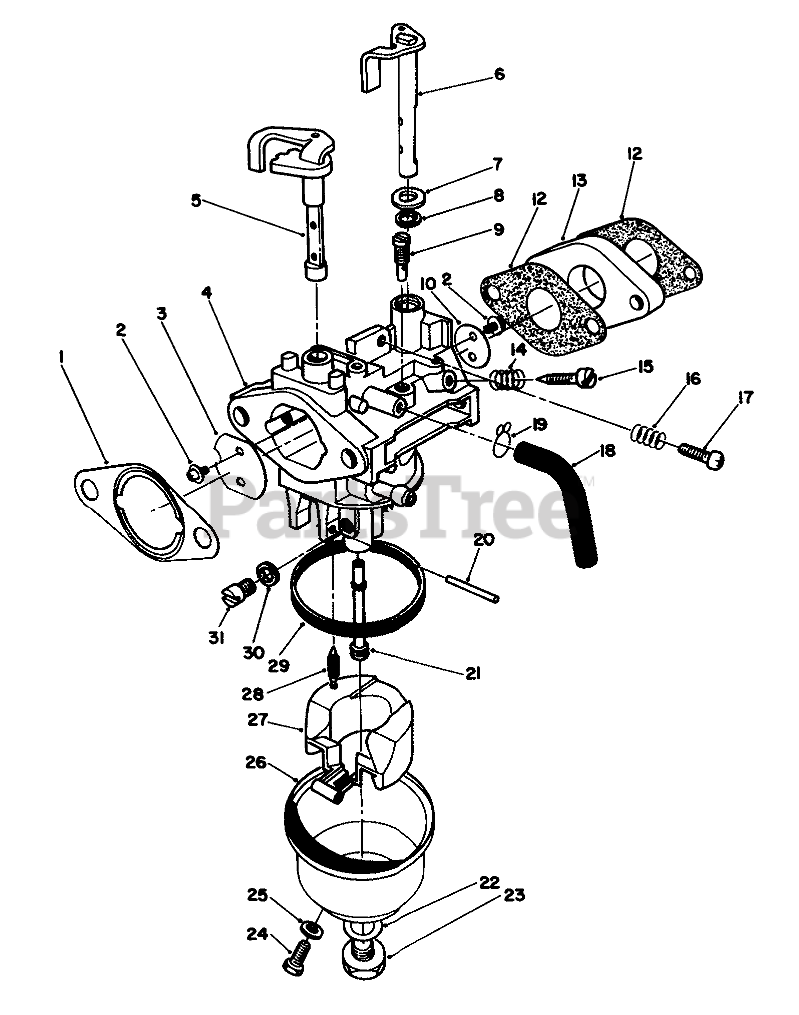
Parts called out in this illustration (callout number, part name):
1	GASKET F/W ENGINE
2	Screw
3	VALVE
4	Body-Carburetor
5	SHAFT
6	SHAFT
7	WASHER
8	Seal-Throttle Shaft
9	PILOT JET
10	VALVE
12	Gasket-Carburetor
13	CARB INSULATOR
14	SPRING-PILOT SCREW
15	ADJUSTER
16	SPRING-PILOT SCREW
17	SCREW
19	CLAMP
20	Pin
21	NOZZLE
22	GASKET
23	SCREW
24	SCREW
25	GASKET
27	Float
28	NEEDLE
29	FLOAT BOWL GASKET
30	SPACER
31	MAIN JET
